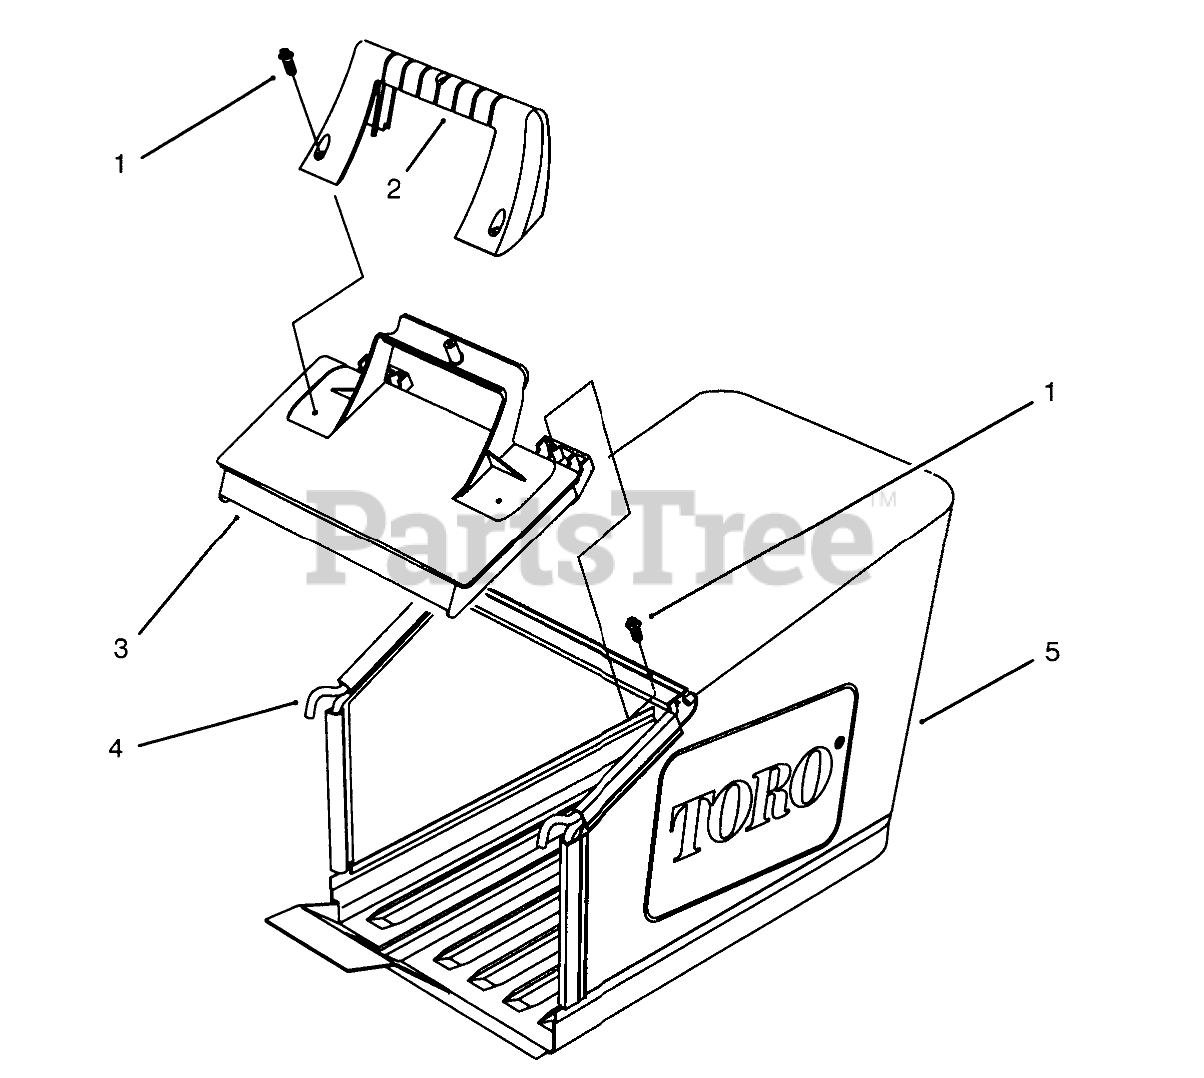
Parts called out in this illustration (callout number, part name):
1	SCREW-TAPTITE
2	HANDLE-DOOR
3	DOOR-BAG
4	Frame
5	GRASS BAG 48CM W/PAN
